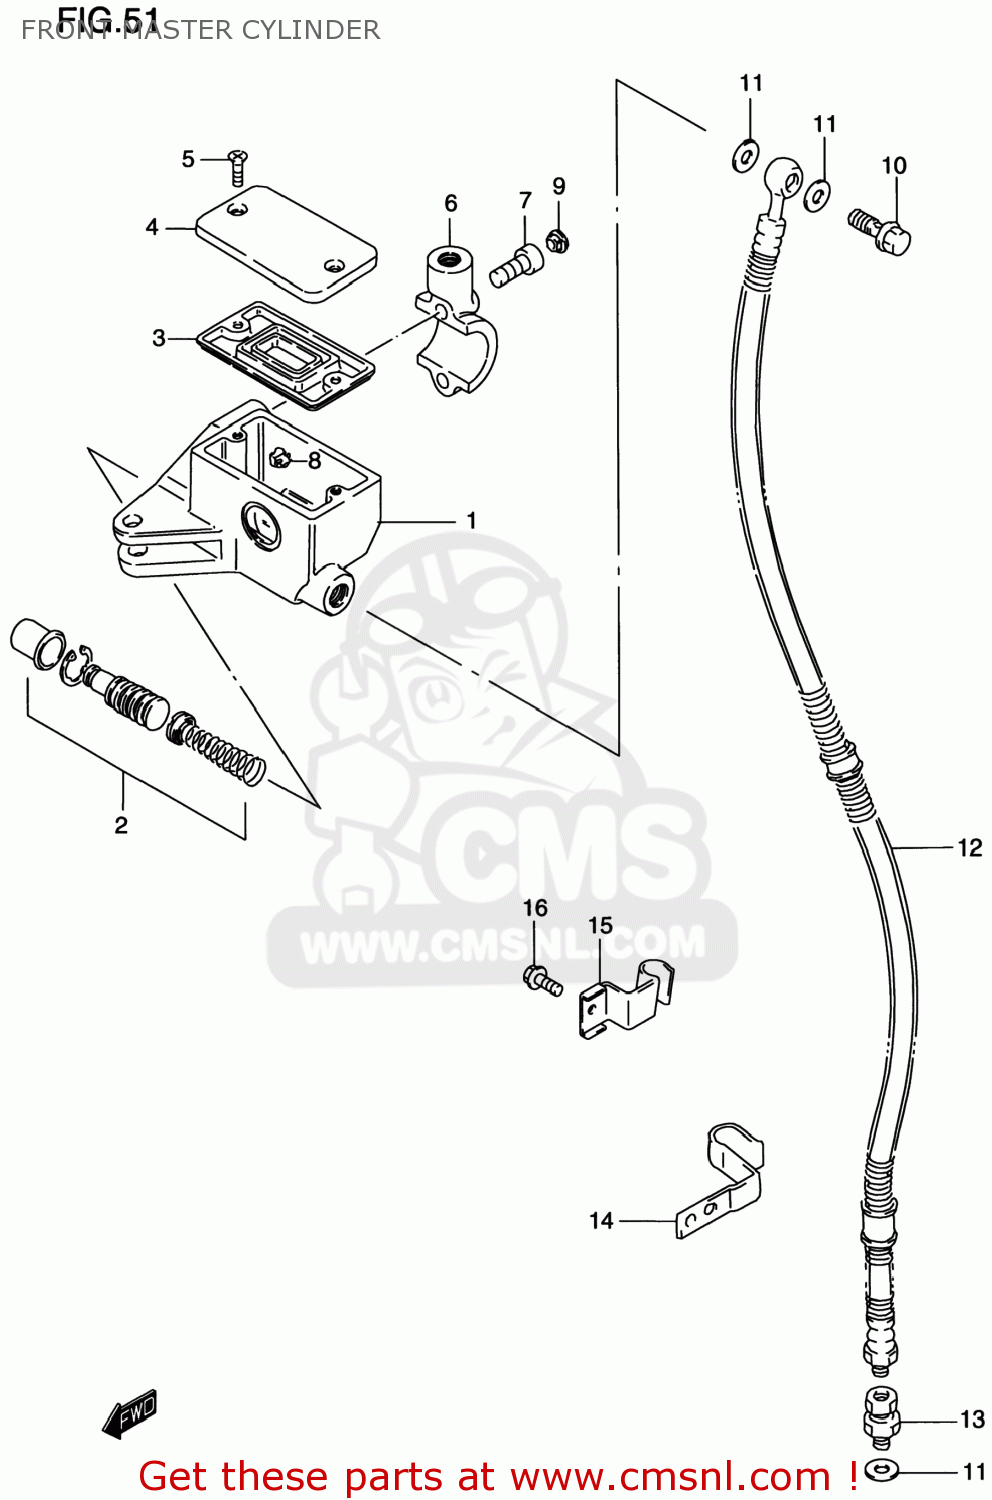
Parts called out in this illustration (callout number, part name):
1	CYLINDER ASSY,FR MASTER
2	PISTON/CUP SET
3	4
4	CAP
5	SCREW
6	HOLDER
7	BOLT
8	PROTECTOR
9	CAP(OD:10)
10	BOLT UNION
11	WASHER(10X15X1.5)
12	HOSE,FR BRAKE
13	ADAPTER,BRAKE HOSE
14	GUIDE,BRAKE HOSE
15	GUIDE,BRAKE HOSE
16	BOLT
